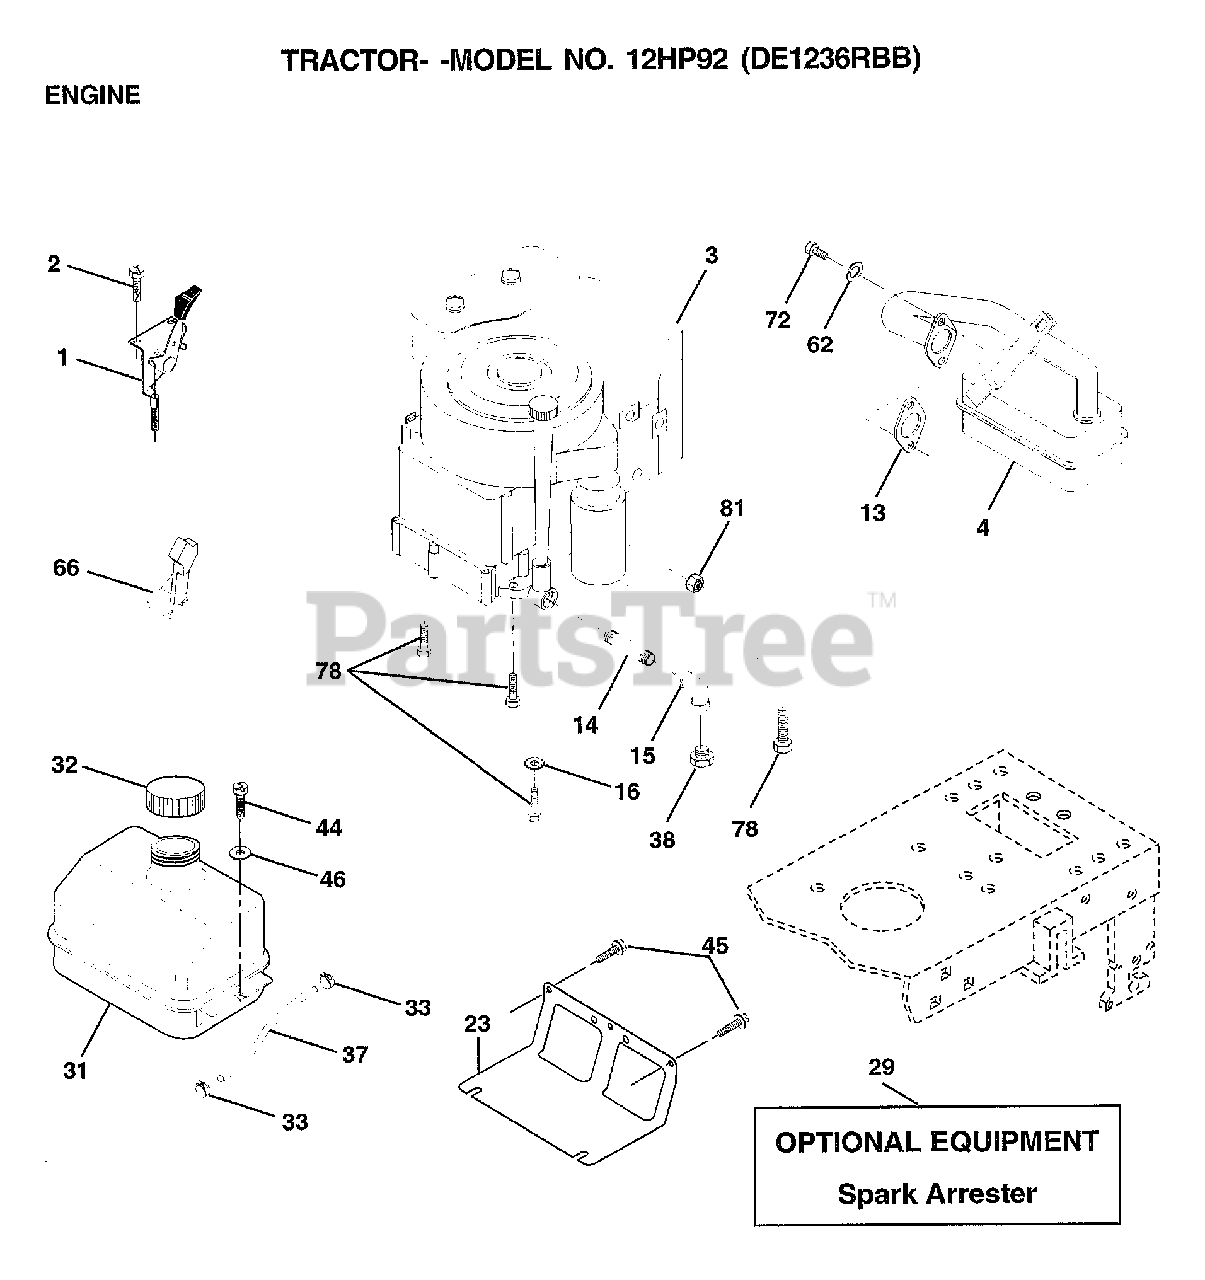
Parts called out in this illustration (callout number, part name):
1	CONTROL.THTL.23.5
2	SCREW LT
4	MUFFLER
14	PIPE NIPPLE
15	ELBOW
16	LOCKWASHER
23	SHIELD BROWNING
31	TANK.FUEL.LT.
32	CAP ASM FUEL
33	HOSE CLAMP
37	LINE FUEL
44	SCREW
45	SCREW
46	WASHER
62	LOCKWASHER
66	"STOP,DASH THROTT"
72	SCREW
78	SCREW
81	NUT
